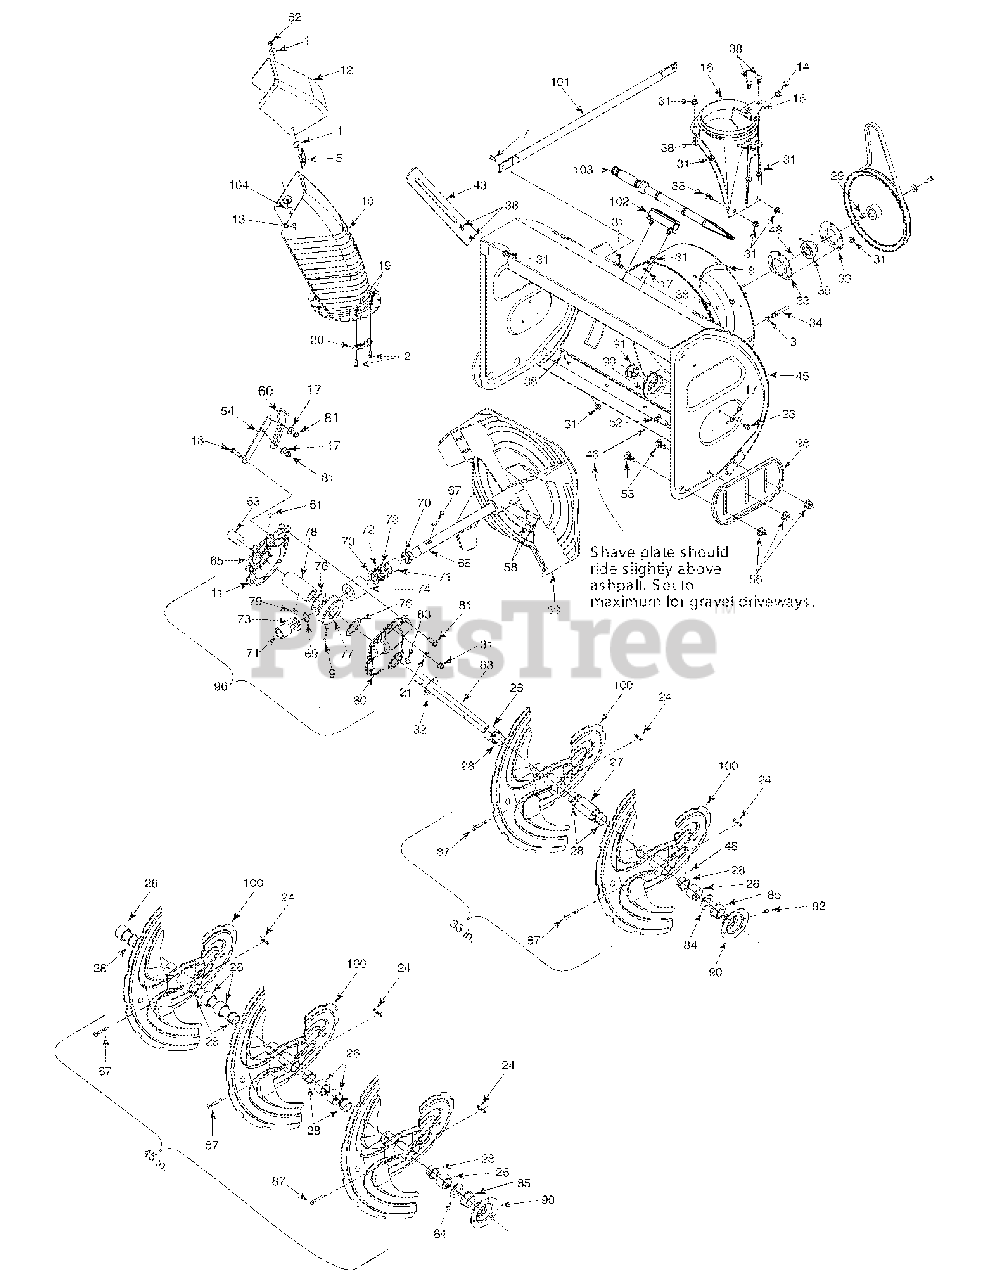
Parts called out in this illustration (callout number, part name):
1	Flat Washer .344 ID x .875 OD
2	Hex. Scr. 1/4-20 x 1.00 Gr. 5
3	Lockwasher 3/8" ID
5	Handle Knob Assembly
7	Hex Hd Cap Scr. 5/16-18 x .75 Gr. 5
10	Extended Lower Black Plastic Chute
11	Ultra Grey Loctite #5699
12	Upper Black Plastic Chute
13	Carriage Bolt 5/16-18 x 1.00" Lg
14	Plastic Bushing .380 ID
16	Chute Adapter
17	Cupped Washer .345 ID x .88 OD x .06
18	Hex Screw 5/16-18 x 1.25
19	Hex Flange L-Nut 1/4-20 Gr. F Nylon
20	Chute Flange Keeper
21	Lockwasher 5/16" ID
22	Flange L-Nut 5/16-18 Gr. 5 Nylon
23	Hex Wash HD Tap Scr 5/16-18 x .75
24	Bow Tie Cotter Pin
26	Spacer 1.5 x 1.0 ID x 1.0" Lg.
27	Spacer 1.5 x 1.0 ID x 2.5" Lg.
28	Flange Bushing 1.05 ID x 1.16 OD
29	#9 HI-Pro Key 3/16 x 3/4 Dia HT
30	Self-Aligning Bearing .875 ID
31	Hex Flg. L-Nut 5/16-18 Gr. F Nylon
32	Flat Washer 1.010 x 1.88 x .060
33	Bearing Housing
34	Belt Keeper Studs 3/8-16 x 2.75
38	Carriage Bolt 5/16-18 x .75
48	Arctic Grease
52	Carriage Bolt 3/8-16 x 1.00 Gr. 5
53	Carriage Bolt 3/8-16 x .75" Lg.
56	Hex Flange L-Nut 3/8-16 Gr. F Nylon
58	Spring Spirol Pin Heavy - 5/16 dia x 1.7
61	Barbed Plug
63	Spiral Axle - Auger Shaft; 33" Standard Serrated, Heavy Duty w/brace
63	Spiral Axle - Auger Shaft; 45" Standard Serrated, Heavy Duty w/brace
65	Gear Housing Half - RH
67	#9 HI-Pro Key 3/16 x 3/4 Dia HT
68	Auger Drive Shaft
69	Snap Ring for .875 dia. shaft
70	Oil seal for .875 ID Garlock (76 x 6133)
71	Sleeve Bearing .875 ID
72	Thrust Bearing .88 ID x 1.44 OD x .078
73	Flat Washer .88 ID x 1.4 OD x .125
74	Worm Gear LH Double Thread
76	Flat Washer 1.5 ID x 2.0 OD x .03
77	Worm Gear LH Double Thread (Bronze)
78	Worm Gear Shaft
79	#91 Woodruff Key 1/4 x 3/4 Dia.
80	Gear Housing Half LH
80	Gear Housing Half LH (w/grease fitting hole)
81	Hex Flange Scr. 5/16-18 x .75
82	Hex Ins. L-Nut 5/16-18
83	#91 Woodruff Key 1/4 x 3/4 Dia.
84	Flat Washer
85	Flange Bearing
87	Shear Bolt 5/16-18 x 1.75
91	Flange bearing w/flats
92	Grease Fitting (optional)
96	Worm Gear Box Ass’y
96	Worm Gear Box Ass’y (w/grease fitting)
103	Cleanout Tool
104	Carriage Bolt 5/16-18 x 1.75
